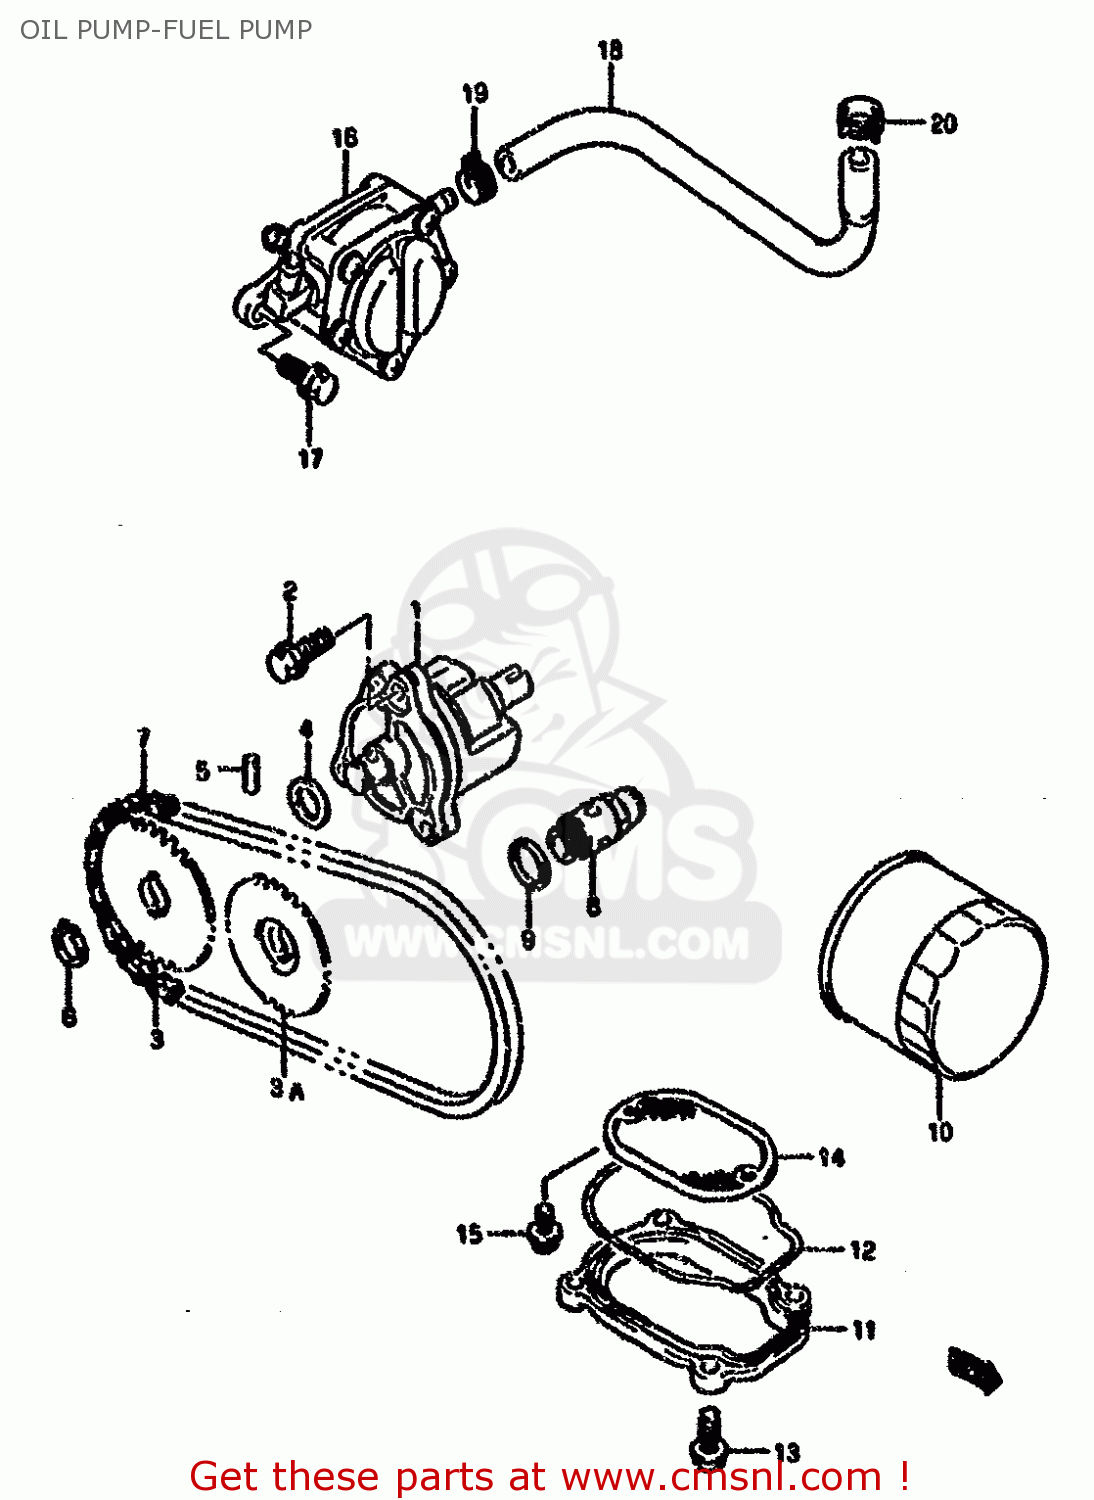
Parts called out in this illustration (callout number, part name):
1	PUMP ASSY,ENGINE OIL
2	BOLT
3	SPROCKET,OIL PUMP DRIVEN
3A	SPROCKET,OIL PUMP DRIVEN
4	SHIM
5	PIN(5X18)
6	CIRCLIP,12 MM
7	CHAIN,OIL PUMP DRIVE
8	VALVE ASSY,OIL RELIEF
9	GASKET(16X22X2) (NAS)
10	FILTER ASSEMBLY,ENGINE OIL
11	CAP,OIL STRAINER
12	O RING,OIL STRAINER CAP
13	BOLT
14	STRAINER,ENGINE OIL
15	SCREW
16	PUMP ASSY,FUEL
17	BOLT
18	HOSE(5.4X11.4X600)
19	CLIP
20	CLIP
